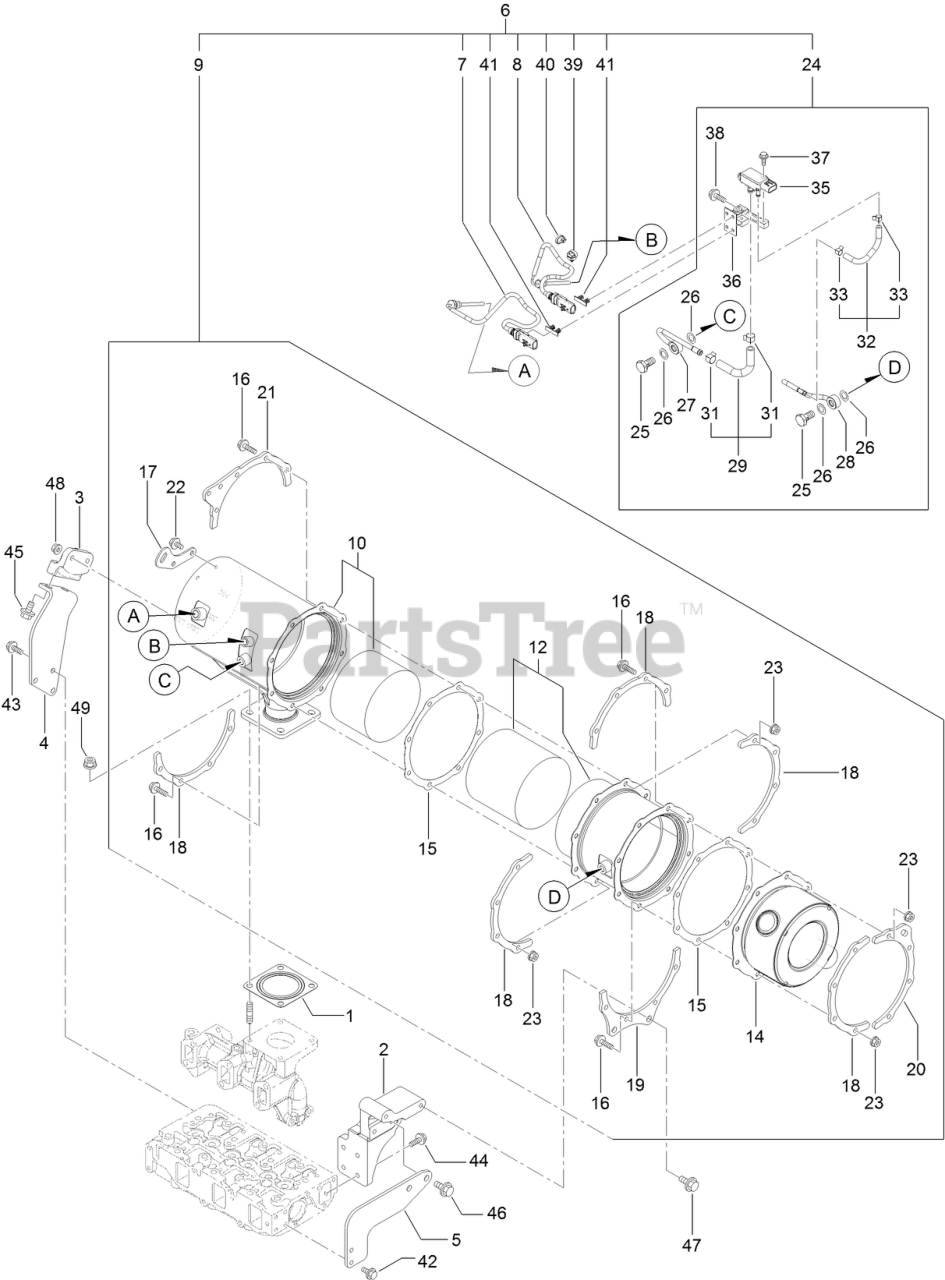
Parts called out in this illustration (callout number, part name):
1	GASKET-SILENCER
2	STAY-D P F
3	STAY-D P F
4	STAY-D P F
5	STAY-D P F
6	D P F UNIT
7	SENSOR-TEMP, EXHAUST
8	SENSOR-TEMP, EXHAUST
9	D P F ASM
10	CASE-D O C
12	CASE-FILTER, SOOT
14	SILENCER-D P F
15	GASKET-D P F
17	LIFTER-D P F
18	STIFFENER-D P F, A
19	STIFFENER-D P F, B
20	STIFFENER-D P F, C
21	STIFFENER-D P F, C
24	PRESSURE SENSOR UNIT
25	BOLT-JOINT, PIPE
26	GASKET-SENSOR
27	SENSOR PIPE ASM
28	SENSOR PIPE ASM
29	EXHAUST HOSE ASM
31	CLIP-HOSE
32	EXHAUST HOSE ASM
33	CLIP-HOSE
35	SENSOR-PRESSURE
36	BRACKET-SENSOR
39	BAND-CLIP
41	CLIP-CONNNECTOR
42	BOLT
43	BOLT
44	BOLT, M8 X 20 PLATED
